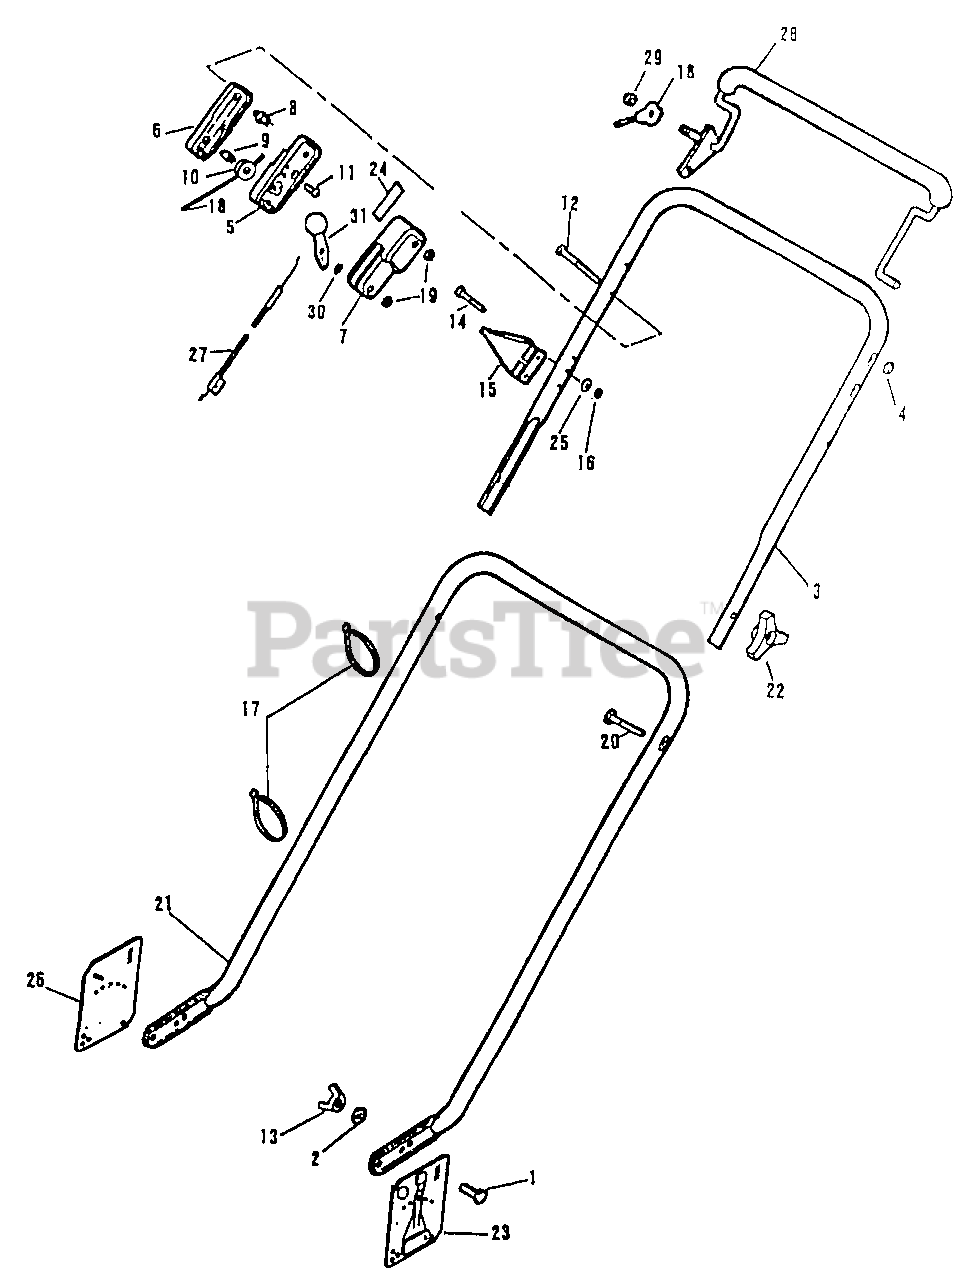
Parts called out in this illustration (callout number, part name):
1	Bolt-Handle Mounting
2	Lock Washer
3	Top Handle
4	Pushnut
5	Control Case-Center
6	Control Case-Outer
7	Control Case-Inner
8	Column
9	Pin
10	Pulley
11	Screw
12	Screw
13	Wing Nut
14	Screw-Truss Head
15	Rope Guide Assembly
16	Locknut
17	Tie Strap
18	Control Cable Assembly
19	Nut-Hex-Centerlock
20	Screw
21	Handle-Bottom
22	Knob
23	Bracket-Handle-L.H.
24	Decal-Throttle
25	Washer
26	Bracket-Handle-R.H.
27	Cable-Throttle
28	Control Lever
29	Nut-Acorn
30	Washer-Spring
31	Lever and Knob Assembly
